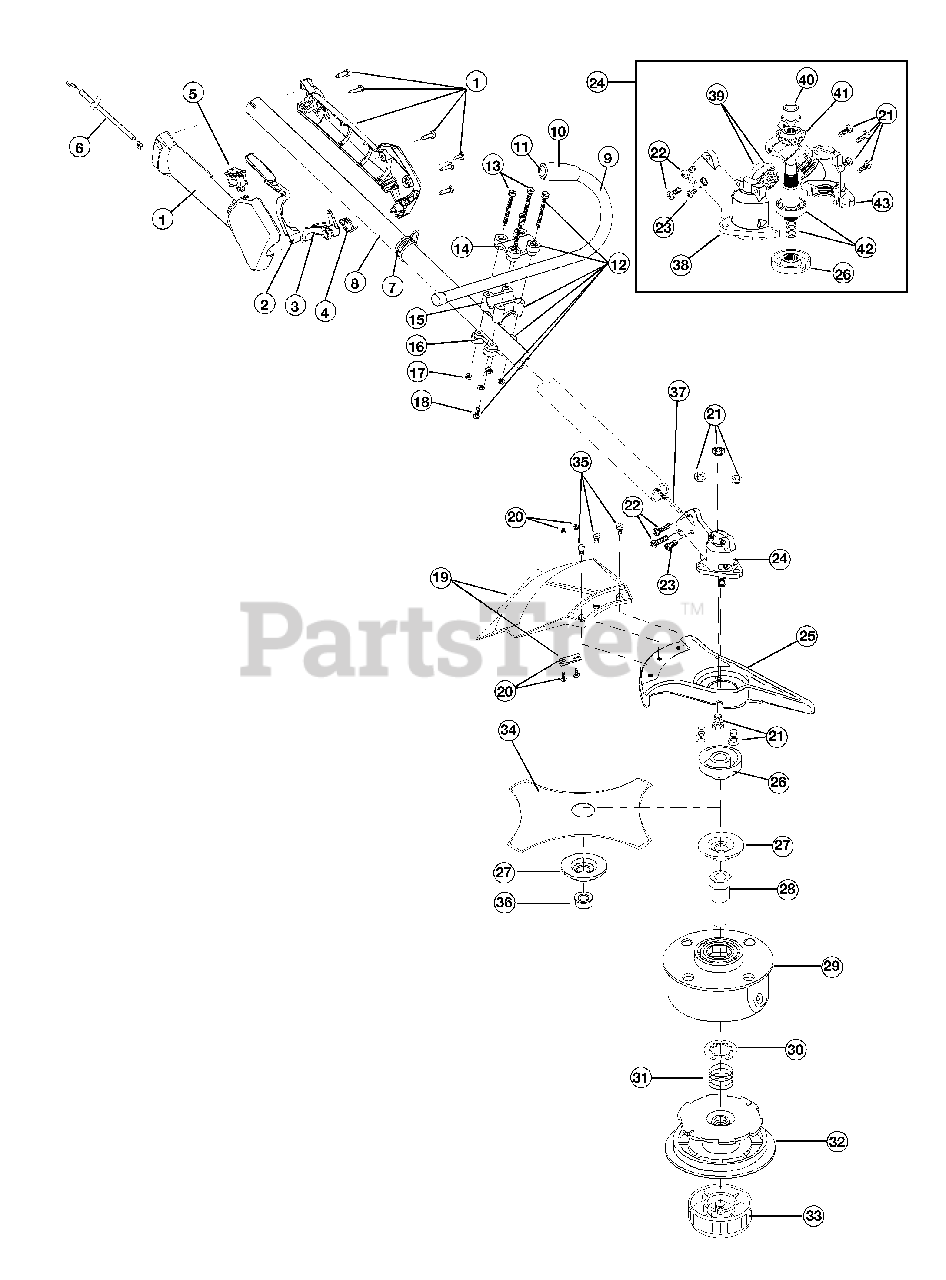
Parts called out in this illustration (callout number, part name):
1	Throttle Housing & Trigger Assembly
2	Throttle Trigger Lock-Out
3	Throttle Trigger
4	Throttle Trigger Spring
5	Switch Assembly
6	Throttle Cable Assembly
7	Harness Clip
8	Upper Drive Shaft Housing Assembly
9	J-Handle Assembly
11	Tube Closure
12	Handle Bracket Assembly
14	Upper Handle Clamp
15	Middle Handle Clamp
16	Lower Handle Clamp
18	Anti-Rotation Screw
19	Shield and Blade Assembly
20	Blade Assembly
21	Shield Mount Screw Assembly
22	Gearbox Mounting Hardware
23	Anti-Rotation Screw
24	Gearbox Assembly
25	Blade Shield
26	Blade Driver
27	Retaining Washer
28	Spool Shaft
29	Outer Spool and Eyelet Assembly
30	Retainer
31	Spring
32	Inner Reel
33	Bump Head Knob Assembly
34	4-Tooth Blade
35	Guard Mount Screws
36	Nut
37	Flexible Drive Shaft
38	Right Housing
39	Pinion Gear Assembly
40	Output Shaft Bushing
41	Output Shaft Gear
42	Output Shaft Assembly
43	Left Housing
